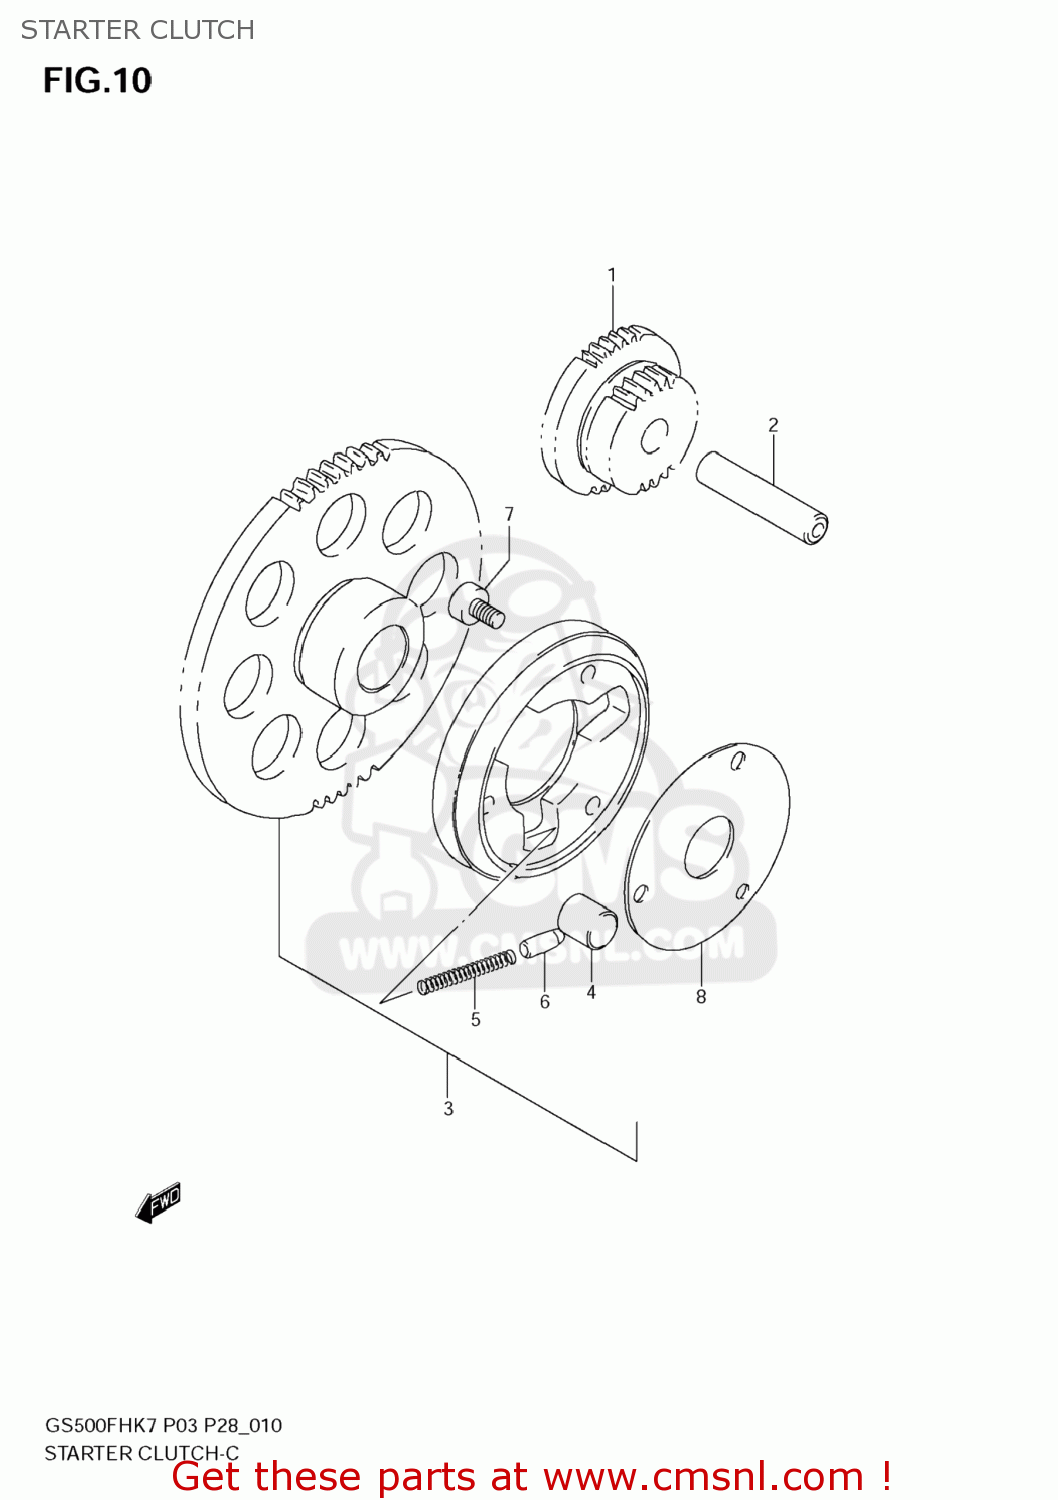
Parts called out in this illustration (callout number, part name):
1	GEAR,STARTER IDLE
2	PIN(7.4X13X56)
3	CLUTCH SET, STARTER
4	ROLLER(15X13)
5	SPRING
6	PIECE,PUSH
7	BOLT(8X16)
8	SHIM,STARTER CLUTCH HUB
